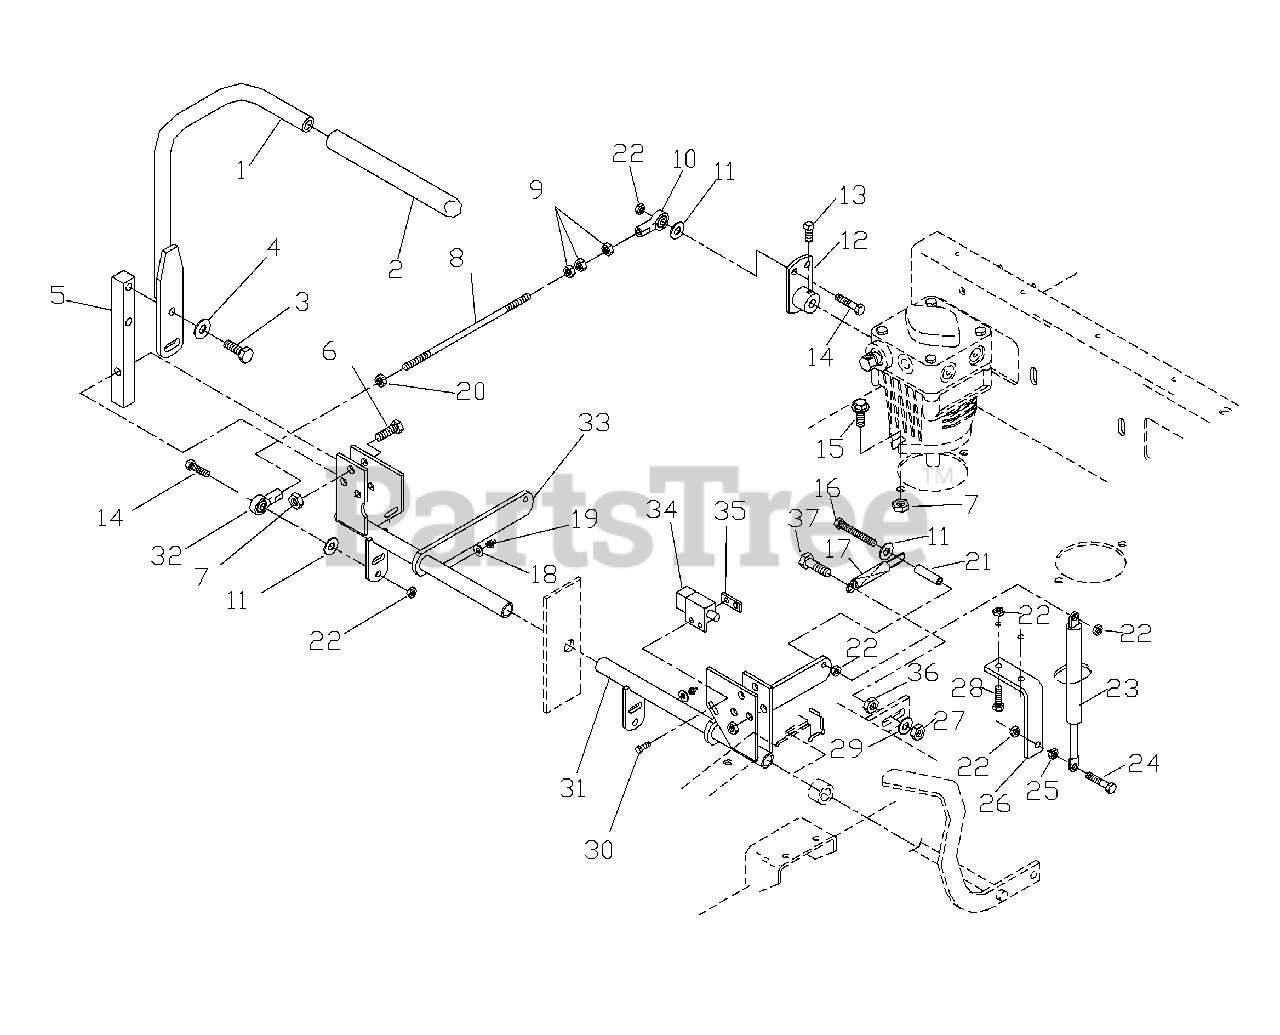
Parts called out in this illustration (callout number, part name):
1	CONT. LEVER
3	HCS 3/8C X 1
4	3/8 SPRING WASHER
5	ARM CONT. SHAFT
6	HCS 3/8C X 1 1/2
7	NUT 3/8C CTR. LOCK
8	PUMP CONTROL LINK
10	BALL JOINT RT.
11	5/16 FLAT WASHER
12	PUMP LEVER
13	5/16C X 5/8 V POINT
14	HCS 5/16C X 1
15	HCS 3/8C X 1
16	TAPBOLT 5/16C X 2.25
17	REV. DETENT SPRING
19	ZERK
20	NUT 5/16F LH.
22	.5/16C CTR. LOCK
24	HCS 5/16C X 1.25
25	5/16C WHIZ NUT
27	3/8C NYLOC
28	HCS 5/16C X 3/4
29	3/8 FLAT WASHER
30	SCREW #10-24 X 5/8
31	CONTROL WLDMT. LEFT
32	BALL JOINT LH.
33	CONTROL WLDMT. RIGHT
35	TAPPED PLATE
36	3/8C WHIZ NUT
37	HCS 3/8C X 2
38	HOSE CLAMP
